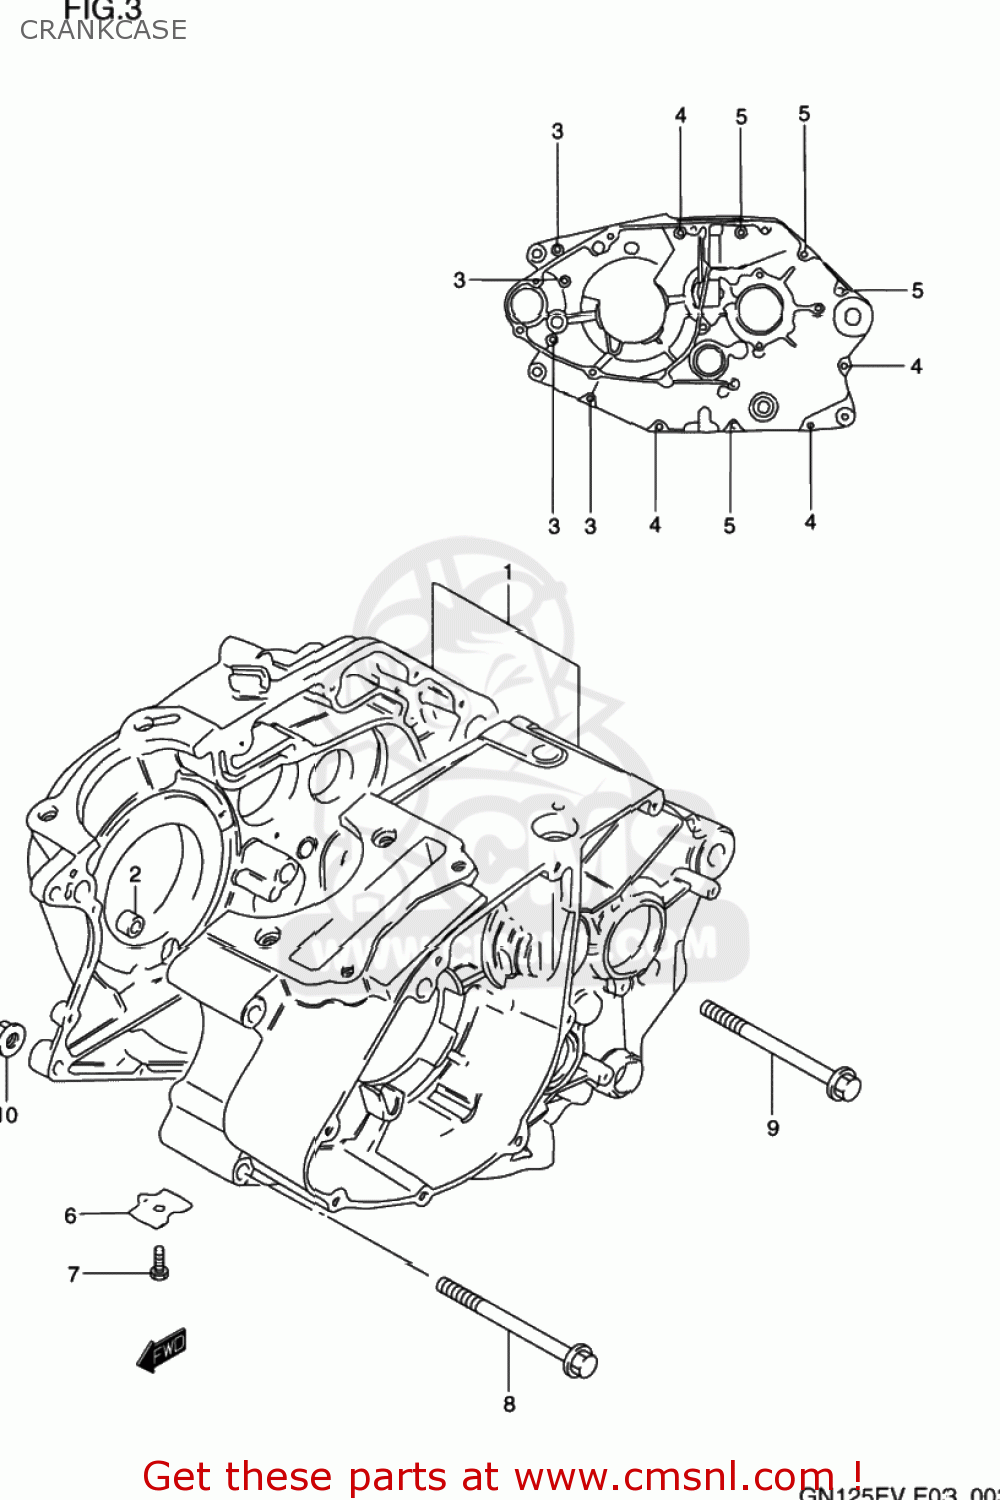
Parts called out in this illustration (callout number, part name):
1	CRANKCASE ASSEMBLY
2	PIN
3	BOLT
4	BOLT
5	BOLT
6	PLATE,OIL GALLERY PLUG
7	BOLT
8	BOLT(8X80)
9	BOLT(8X88)
10	NUT
